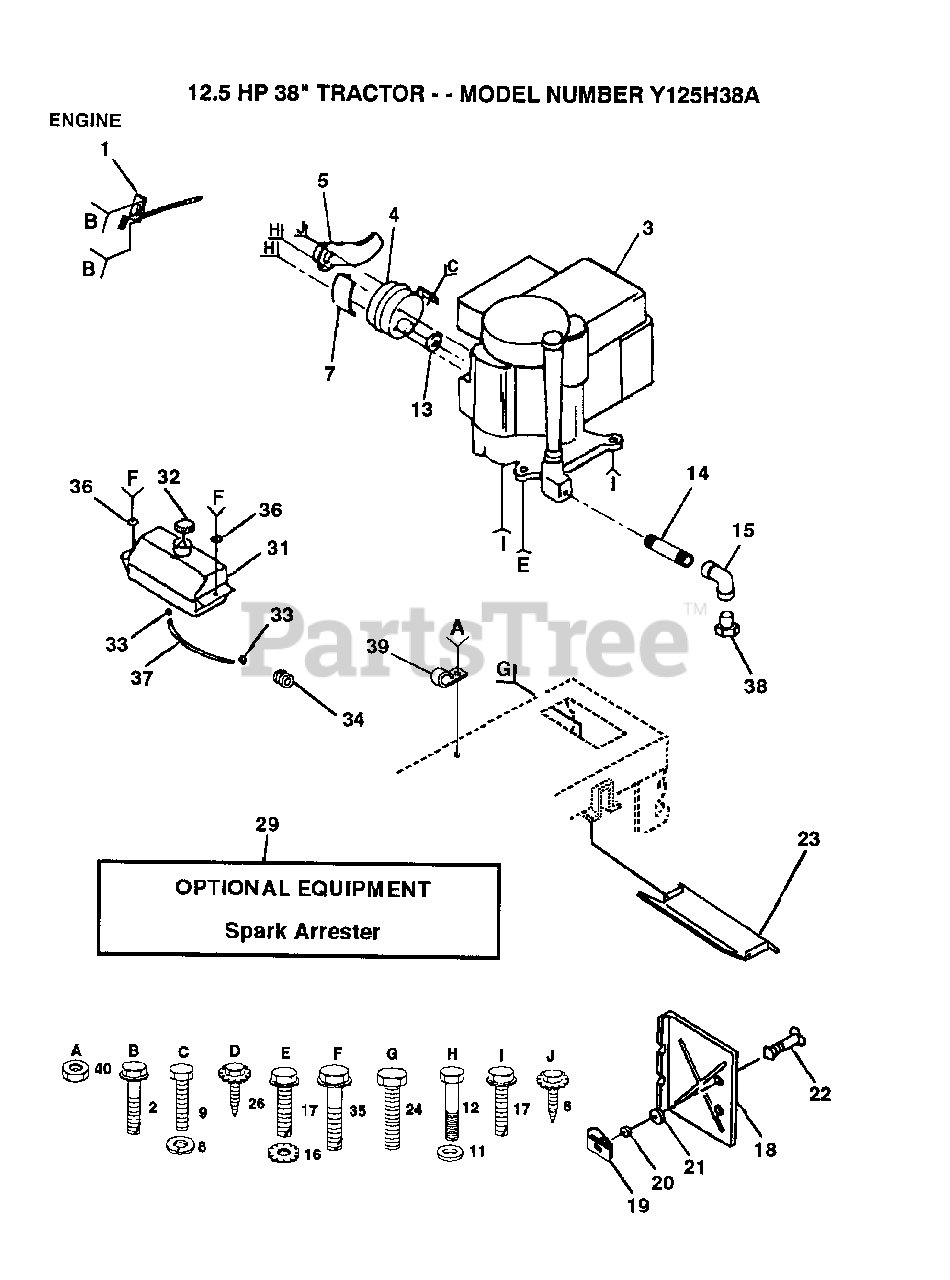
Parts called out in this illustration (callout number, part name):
1	THROTTLE CONTROL
2	SCREW LT
4	MUFFLER LTV
5	DEFLECTOR MUFFLER
7	SHIELD HEAT LTV
8	LOCKWASHER
9	BOLT
11	WASHER T
12	"BOLT,HEX"
14	PIPE NIPPLE
15	ELBOW
16	LOCKWASHER
17	SCREW
19	RECEPTACLE LT
20	RETAINER LT
21	WASHER
22	STUD.1/4.TURN
23	HEAT SHIELD
24	SCREW
31	TANK.FUEL.LT.
33	HOSE CLAMP
35	SCREW HEX CRT
36	WASHER
39	CLIP T
